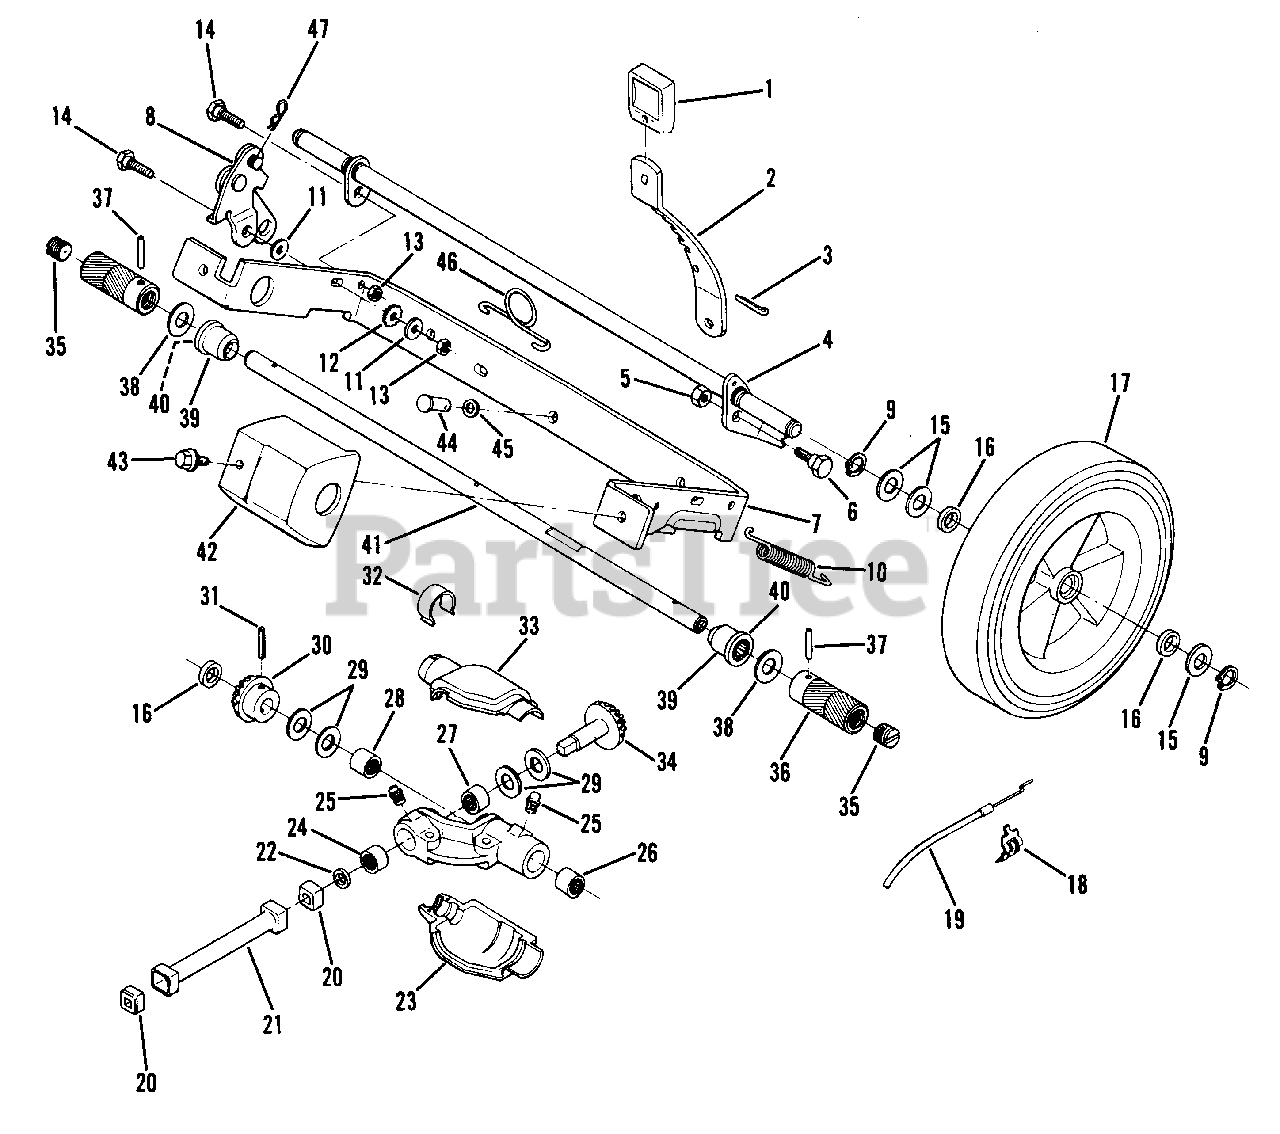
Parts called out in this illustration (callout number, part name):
1	Knob-Rear Height Adjust Lever
2	Lever-Rear Height Adjust
3	Cotter Pin
4	Axle Assembly
5	Locknut
6	Bolt
7	Bracket-21" Axle
8	Clutch Assembly
9	Retaining Ring
10	Spring
11	Washer
12	Lockwasher
13	Stop Nut
14	Bolt
15	Washer
16	Washer-Felt
17	Wheel-Rear
18	Clip
19	Cable-Starter Interlock
20	Bushing
21	Tube-Drive
22	"O" Ring-Spacer
23	Cover-Gear Bottom
24	Needle Bearing-Sealed
25	Zerk Fitting
26	Needle Bearing-Sealed
27	Needle Bearing
28	Needle Bearing
29	Washer
30	Gear-Drive
31	Roll Pin
32	Clamp
33	Cover-Gear Top
34	Gear-Driven
35	Plug
36	Drive Roller-L.H.
37	Pin-Spiral
38	Washer
39	Sleeve & Bearing Assembly
40	Needle Bearing
41	Shaft
42	Guard-Roller
43	Screw-Sems
44	Pin-Rear Height Adjust Lever
45	Spring Washer
46	Spring-Height Adjust
47	Lock Pin
